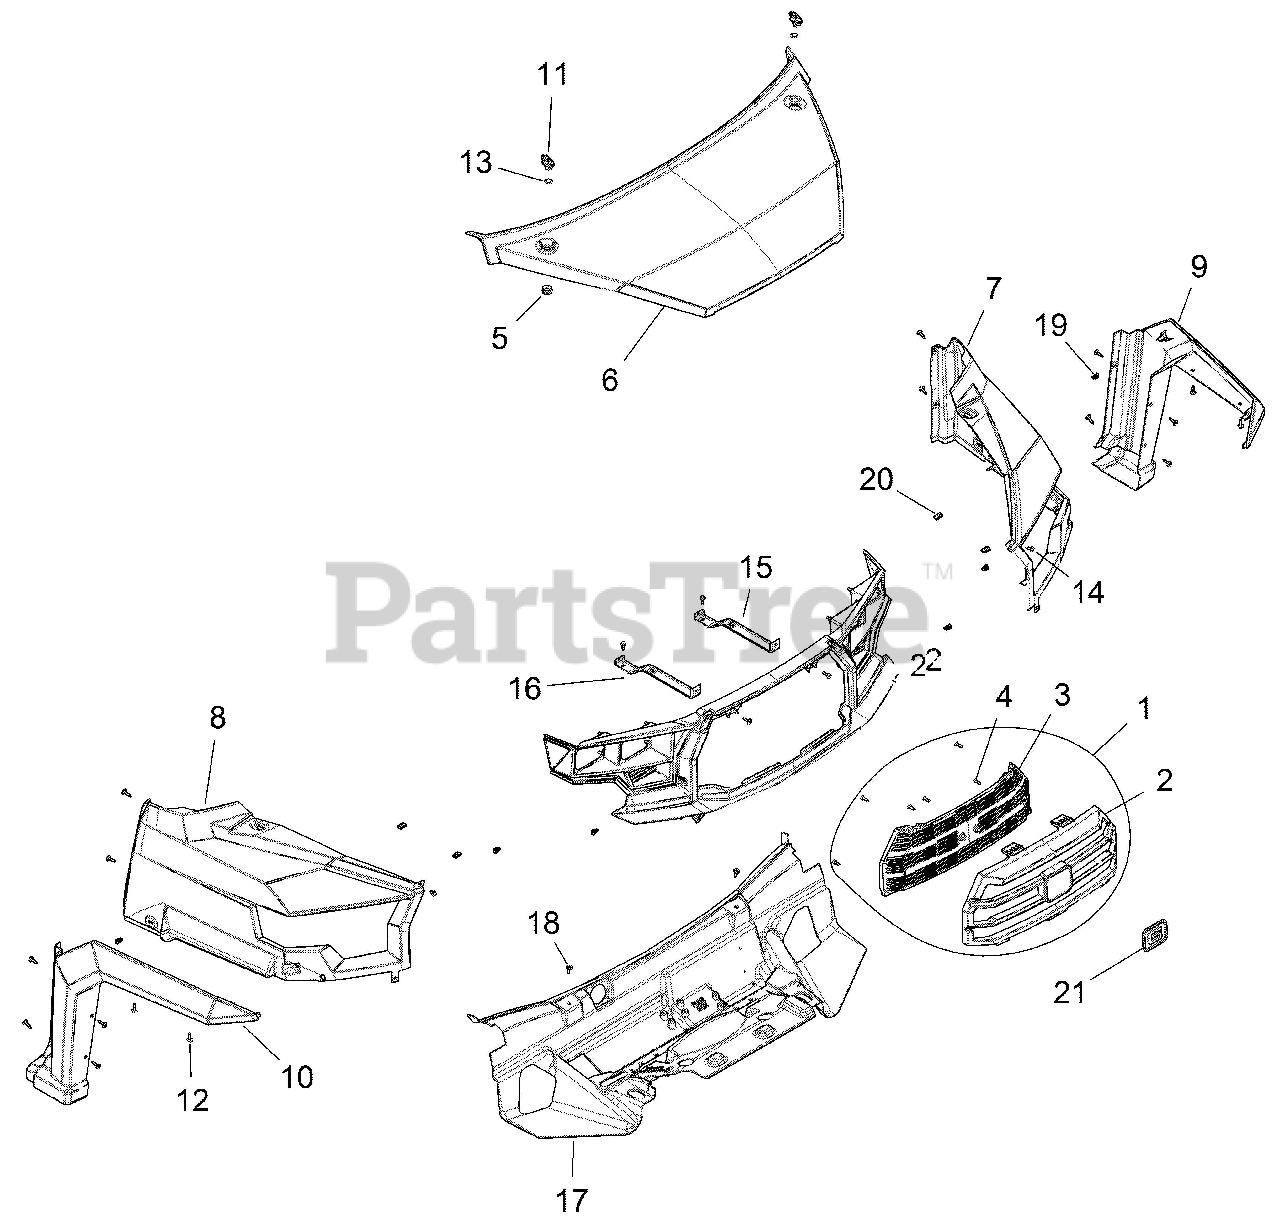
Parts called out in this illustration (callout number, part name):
1	ASM., GRILL, GRAVELY
2	GRILL, FRONT, UPPER, BLACK
3	GRILL, UPPER, TRIM
4	SCR-TXPH-#14 X .75 HI-LO RIE
5	GROMMET-LATCH
6	HOOD-ARIENS,INDY RED
7	FENDER-FRONT,LH,ARIENS,I RED
8	FENDER-FRONT,RH,ARIENS,I RED
9	FLARE-FENDER,FRONT,LH,ARIENS
10	FLARE-FENDER,FRONT,RH,ARIENS
11	LATCH, 1/4 TURN
12	SCR-TXTH-M6X1.0X25 RIE
14	RIVET-TUFLOK,.315-.325X.787 (5
15	BRACKET, BUMPER, FRONT, UPPER, LH
16	BRACKET, BUMPER, FRONT, UPPER, RH
17	LINER-HOOD,BLK
18	SCR-M6X1.0X20,HXHD,FLG,TDFM,BL
19	CLIP, DASH TRIM METAL
20	CLIP-U SPEED NUT
22	BEZEL-HEADLIGHT
